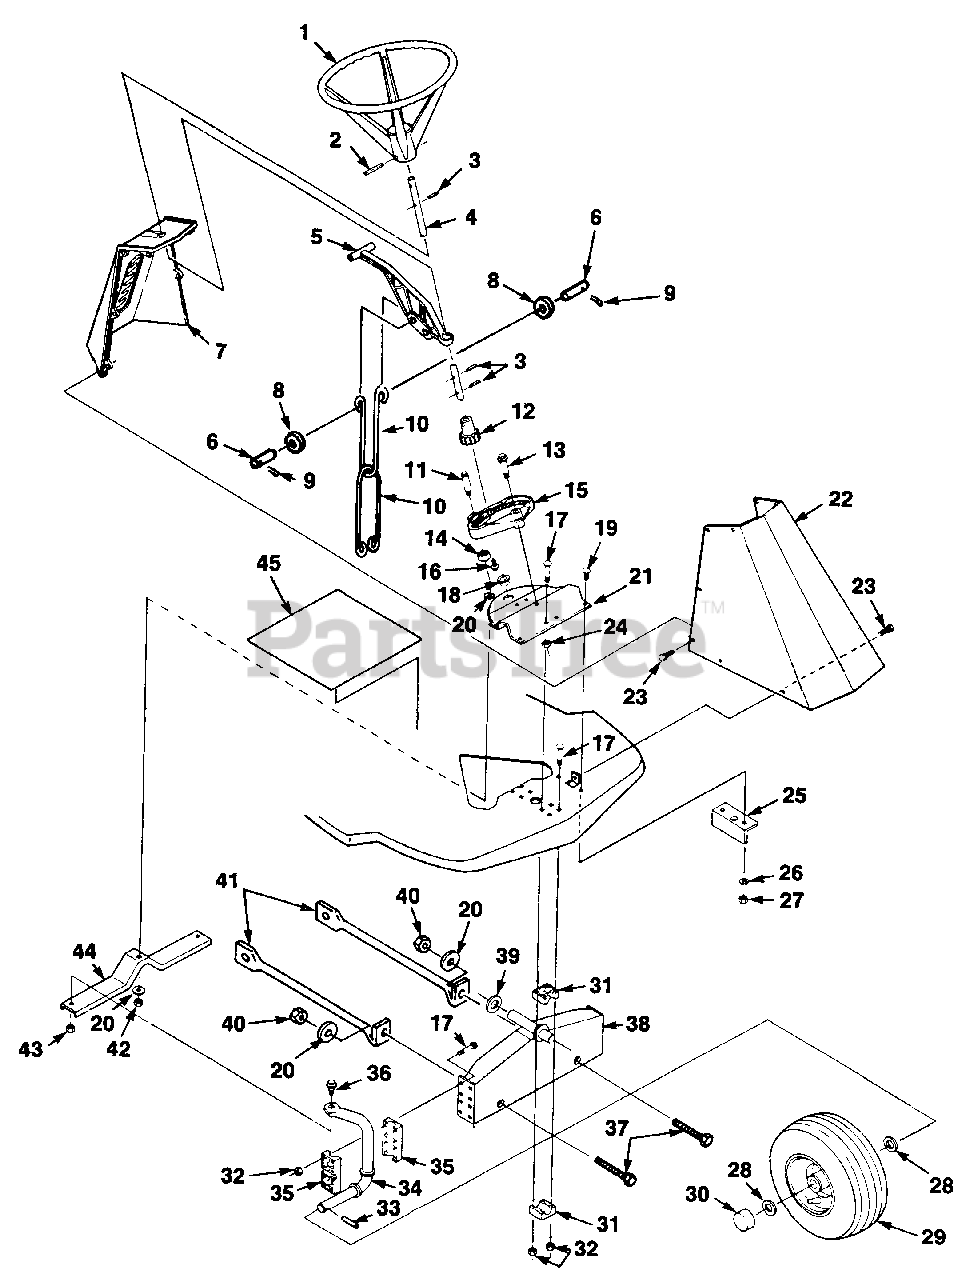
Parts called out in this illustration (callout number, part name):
1	STEERING WHEEL
2	PIN- Roll
4	SHAFT- Steering
5	HANDLE- Lift
6	PIN- Retainer
7	PANEL- Console
8	WASHER- Flat 1/2"
9	PIN- Cotter
10	LINK- Lift
11	STUD- Steering
12	PINION- Steering
13	BOLT- Axle
14	BUSHING- Ball
15	SECTION- Steering
16	SCREW- 1/4-20 x 1/2"
17	BOLT- Rd. hd. sq. 1/4-20 x 1 3/4"
19	BOLT- 1/4-20 x 3/4"
20	WASHER- Plain 3/8"
21	BRACKET- Reinforcement
22	SUPPORT- Steering
23	SCREW- Hex washer 1/4-14
24	NUT- Hex 3/8-16
25	BRACKET- Axle
26	WASHER- Lock 1/4"
27	NUT- Hex 1/4-20
29	TIRE & HUB
31	BEARING- Front axle
32	NUT- Hex centerlock 1/4-20
33	PIN- Roll
34	SPINDLE- Wheel R.H.
35	BEARING- Spindle
36	BRACKET- Axle
37	SCREW- Hex hd. 3/8-15 x.625
38	FRONT AXLE
40	NUT- Hex center lock 3/8-16
41	SUPPORT- Front axle
42	NUT- Lock 3/8-24
43	NUT- Hex centerlock
44	BRACKET- Steering
45	DECAL- Instruction
